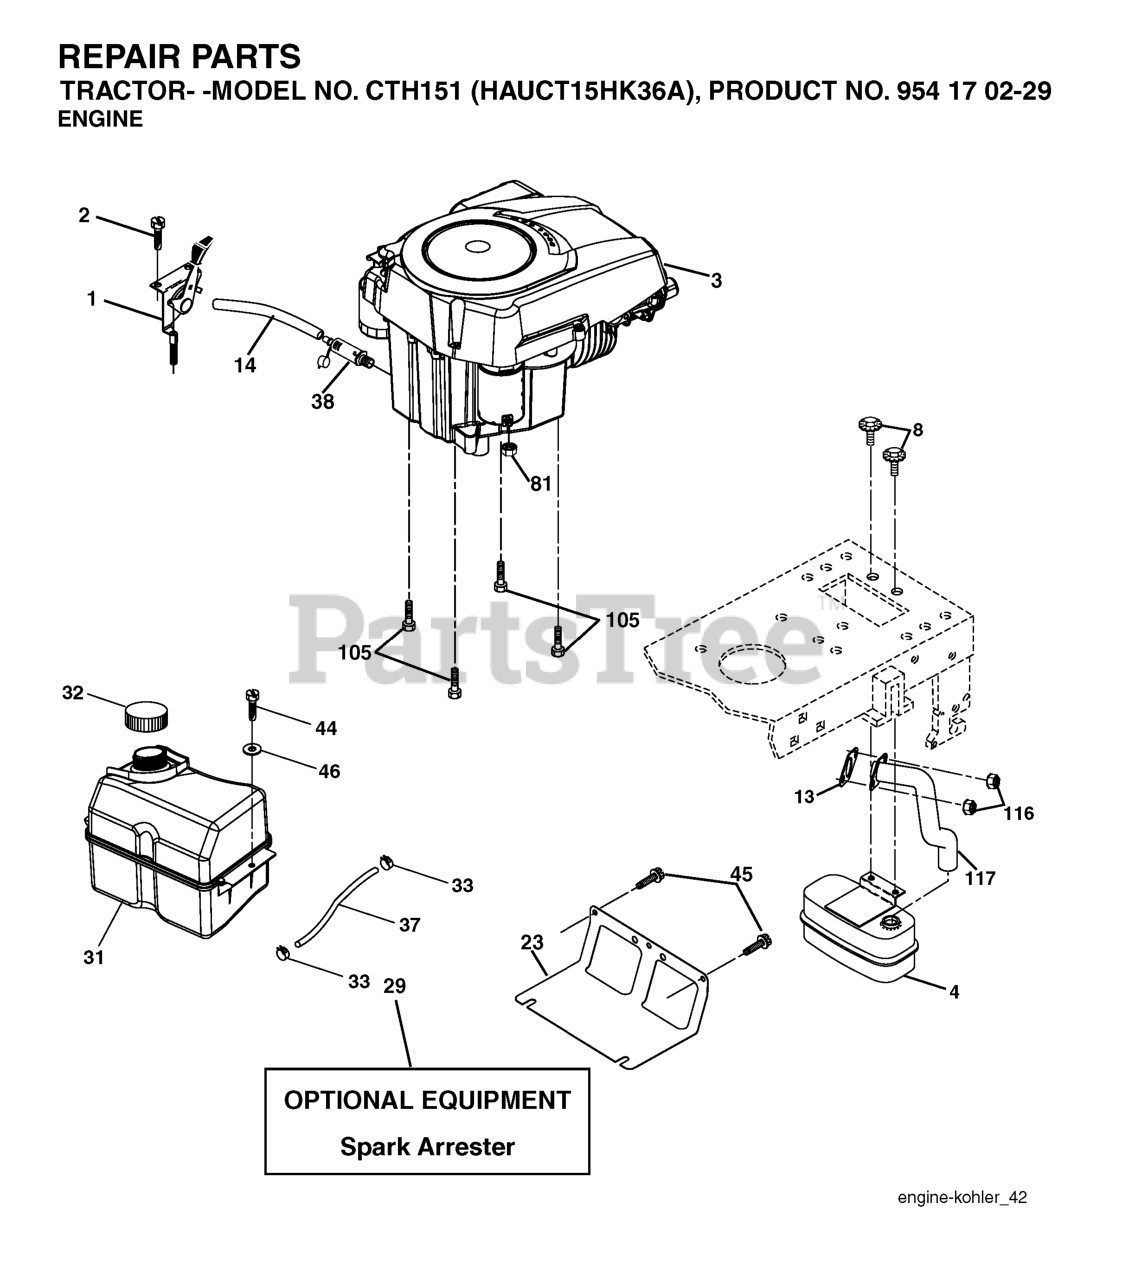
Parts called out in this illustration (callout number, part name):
1	CONTROL.THROTTLE.LT/YT
2	SCREW
4	MUFFLER.SINGLE.CYL.KOHL/B&S
8	BOLT.5/16-18UNCX3/4 W/SEMS.BLK
13	GASKET.EXHAUST.KOHLER
14	TUBE, DRAIN OIL ASM.
23	SHIELD.BROWNING.DBR.GUARD
29	KIT.SPARK ARRESTOR 794945 B&S
31	TANK FUEL
32	FUEL CAP
33	HOSE CLAMP
37	LINE.FUEL.20
38	PLUG DRAIN OIL EASY
44	SCREW HEXWSHR 1/4-20X3/4
45	SCREW, 3/8-16X3/4
81	NUT
105	SCREW 3/8-16X1
116	NUT.HEX.FLANGE.TOPLOCK
117	RP.TUBE.EXHAUST.KOHL.COURAGE
